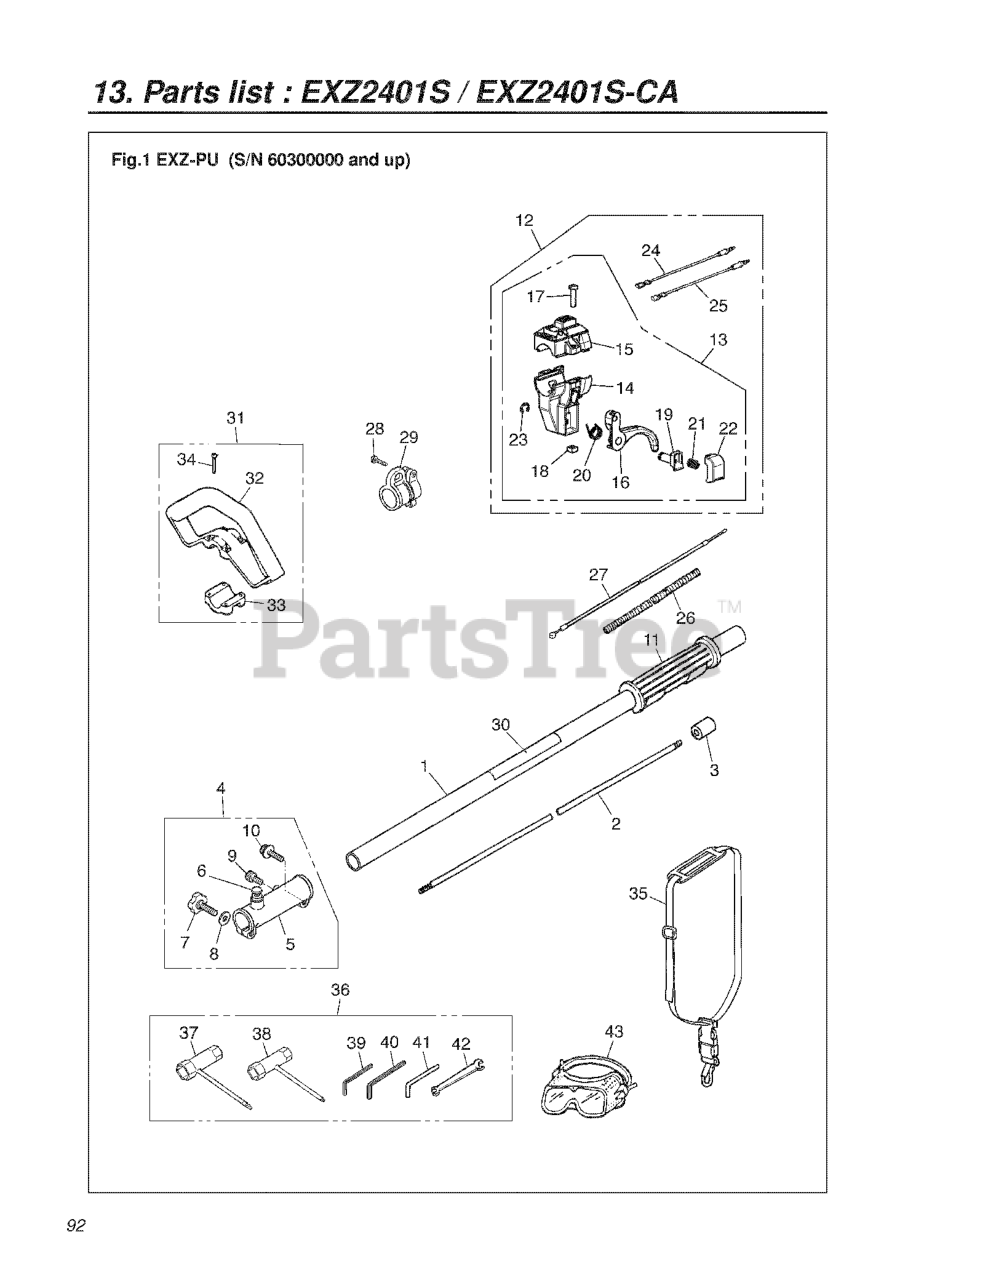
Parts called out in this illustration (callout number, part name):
1	PIPE-C
4	JOINT, PIPE ASSY
5	JOINT
7	KNOB BOLT
9	BOLT M5 X L10 ALLEN BOLT
12	LEVER COMP (RPLS 8488R20343)
13	LEVER (FLEX. LEVER)(RPLS -13)
15	COVER COMP (RPLS 611014410-02)
16	THROTTLE TRIGGER
24	CORD (A), BLACK
25	CORD (B), RED
28	HANGER COMP.
31	HANDLE ASSEMBLY(RPL 397414300)
35	HARNESS-ASSY***
36	TOOL SET
37	SOCKET
40	Wrench Tool
